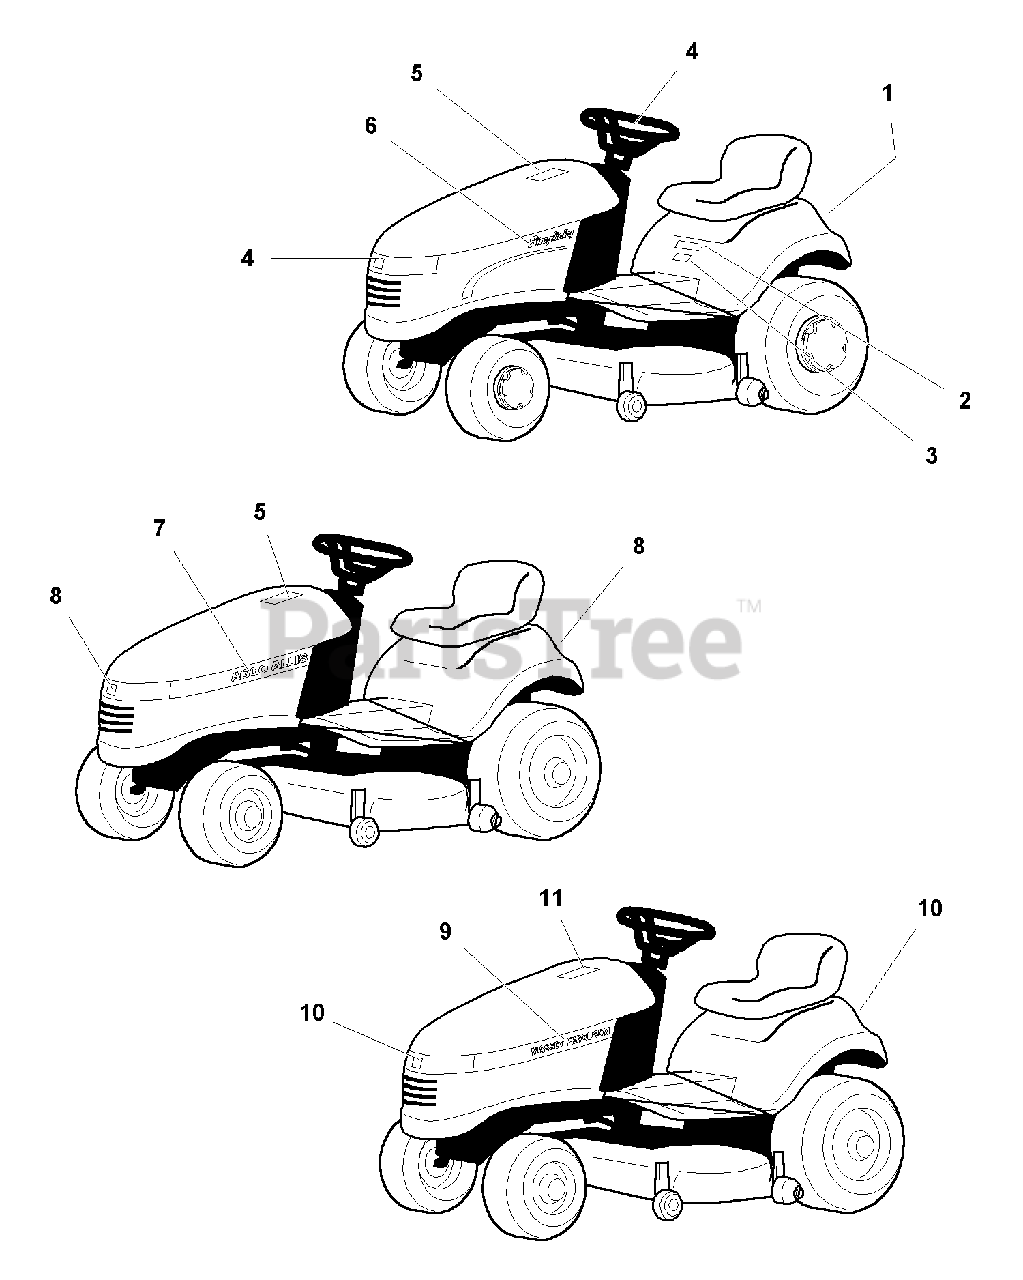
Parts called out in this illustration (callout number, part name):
1	DECAL, Seat Deck, Rear, Simplicity
2	DECAL, Seat Deck, Front, Regent
3	DECAL, Seat Deck, Front, 16-Hydro, Simplicity
3	DECAL, Seat Deck, Front, 15-Hydro, Simplicity
4	DECAL, Icon, Simplicity
5	DECAL, Hood (Underside), Touch-Up Paint, Simplicity & AGCO-Allis
5	DECAL, Hood (Underside), Touch-Up Paint, Massey Ferguson
6	DECAL, Hood, Right, Simplicity
6	DECAL, Hood, Left, Simplicity
7	DECAL, Hood, Left, 516H, AGCO-Allis
7	DECAL, Hood, Right, 516H, AGCO-Allis
7	DECAL, Hood, Left, 515H, AGCO-Allis
7	DECAL, Hood, Right, 515H, AGCO-Allis
7	DECAL, Hood, Left, 517H, AGCO-Allis
7	DECAL, Hood, Right, 517H, AGCO-Allis
8	DECAL, Icon, AGCO-Allis
9	DECAL, Hood, Left, 2516H, Massey Ferguson
9	DECAL, Hood, Right, 2516H, Massey Ferguson
9	DECAL, Hood, Left, 2515H, Massey Ferguson
9	DECAL, Hood, Right, 2515H, Massey Ferguson
9	DECAL, Hood, Left, 2517H, Massey Ferguson
9	DECAL, Hood, Right, 2517H, Massey Ferguson
10	DECAL, Icon, Massey, Ferguson
11	DECAL, Hood (Underside), Touch-Up Paint, Massey Ferguson
